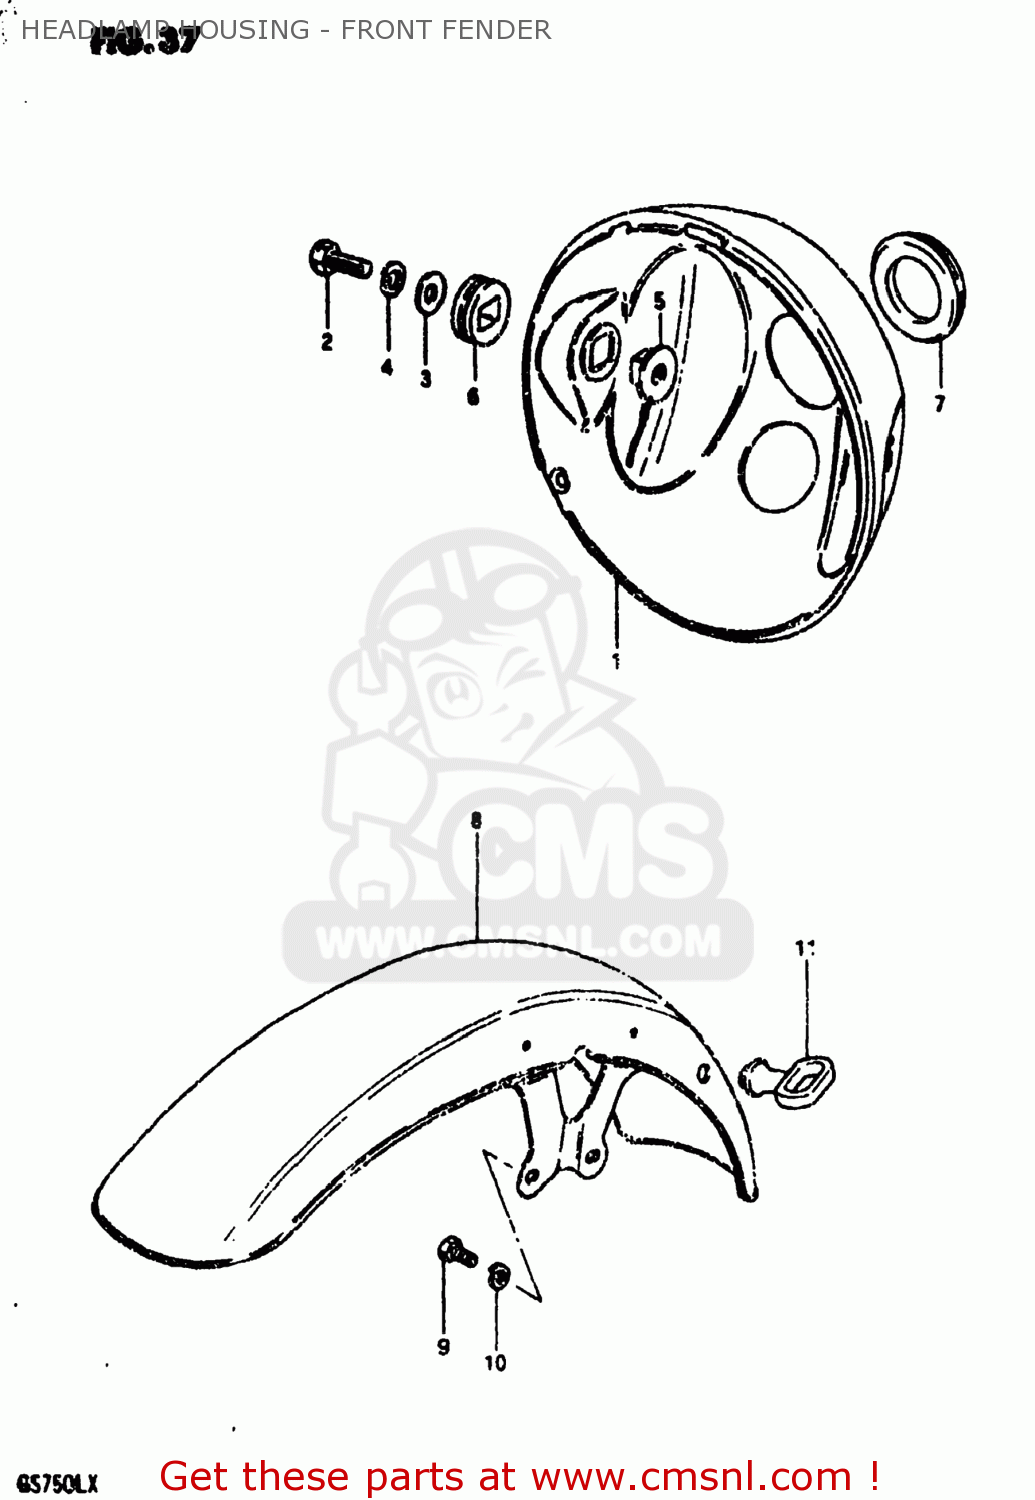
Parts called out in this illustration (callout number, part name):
1	HOUSING,HEADLAMP
2	BOLT
3	WASHER
4	LOCK WASHER
5	SPACER,HEADLAMP HOUSING
6	CUSHION,HEADLAMP HOUSING
7	GROMMET,HEADLAMP HOUSING
8	FENDER,FRONT
9	BOLT
10	LOCK WASHER
11	GUIDE,CABLE
